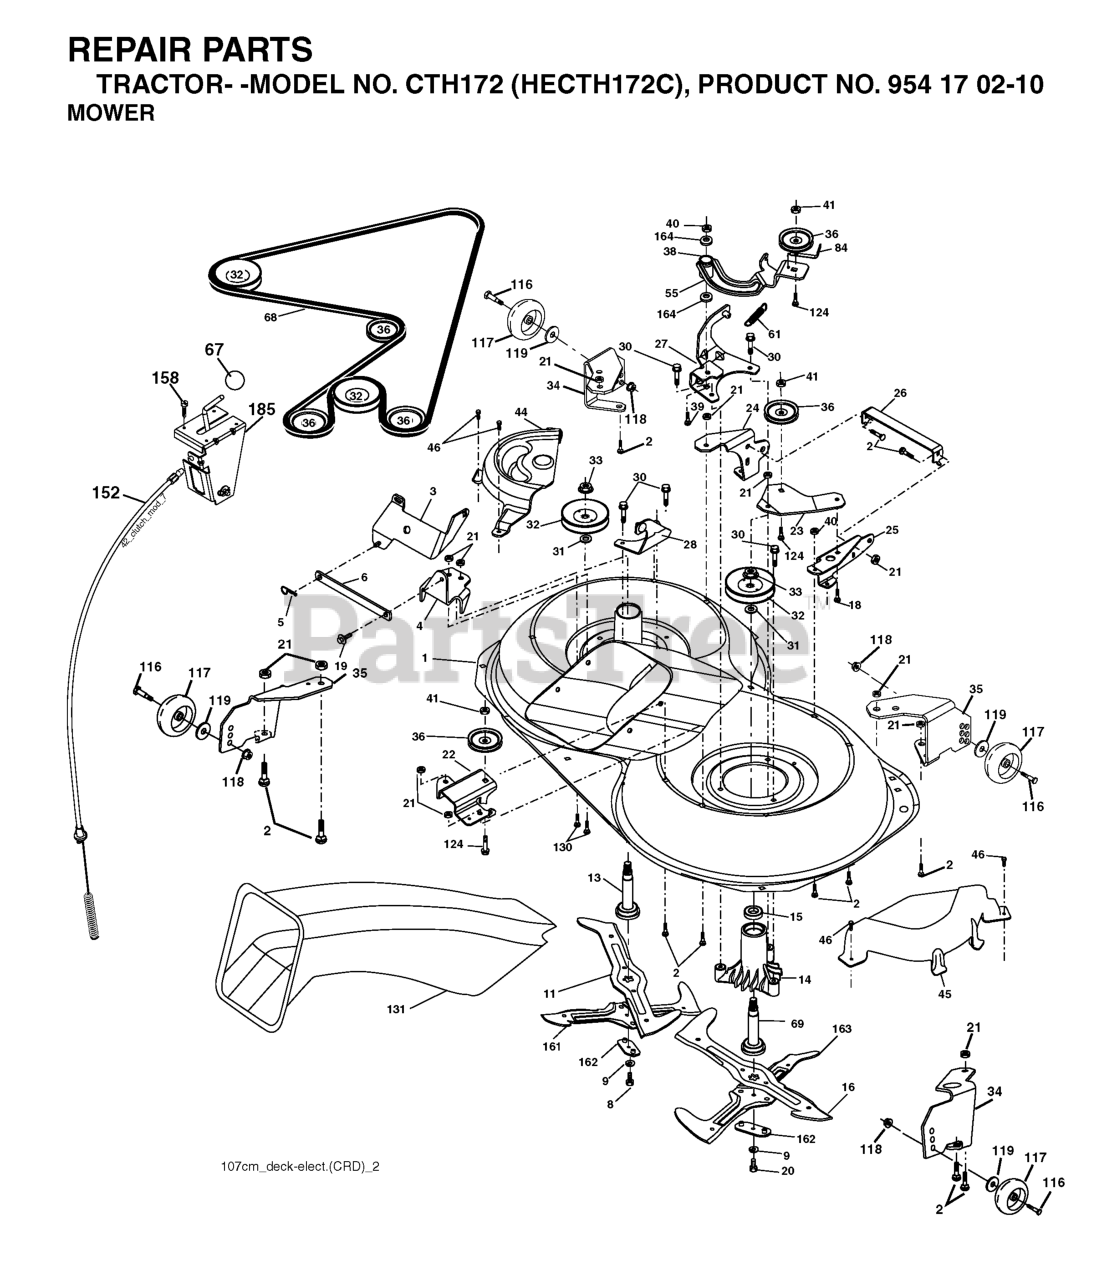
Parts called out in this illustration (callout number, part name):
1	Housing Asm. Mower 107 CRD
2	RP BOLT 5/16-18 X3/4 ZN/YEL GR
5	RETAINER-SPRNG RB
6	BAR.SWAY.92.CRD
8	BOLT.3/8-24X1.25 GR8
9	LOCKWASHER
11	BLADE.3N1.LH.CRD
13	SHAFT ASM VENT
14	HOUSING.MANDREL.VENTED (MACHD)
16	BLADE.3N1.RH.CRD
18	BOLT D
19	BOLT SHD 5/16-18
20	BOLT.3/8-24X1.25GR8. LHTHRD
21	LOCKNUT
22	BRACKET.IDLER.RR.107.CRD
25	BRACKET.SUSPENSION.RF.107.CRD
26	BRACE.SUPT.SUSP.FRT.CRD
28	BRACKET
30	SCREW, WASHER HEAD
31	WASHER.SPACER.MANDREL
33	NUT, FLG TOPLOCK 9/16"
36	PULLEY.IDLER.4.25
41	NUT LOCK FLG 3/8-16 UNC
45	COVER.MANDREL.RH.CRD
46	SCREW.1/4-20X5/8
55	ARM.IDLER.107.CRD
68	HEX-BELT 107 MOWER
69	SHAFT.ASM.W/LWR.BRG.RH.THREAD
84	KEEPER, BELT IDLER
116	SHOULDER BOLT
117	WHEEL GAGE DONUT
118	LOCKNUT
119	WASHER.5/16.FLAT.STE.STD.
124	BOLT.3/8-16X1.50
130	BOLT.CARR.SQNK.5/16-18UNC.X3/4
131	CHUTE BAGGER
158	SCREW
163	BLADE.CROSS.RH.CRD.107
164	BRNG T
185	HEAD ASM. CABLE CLUTCH
